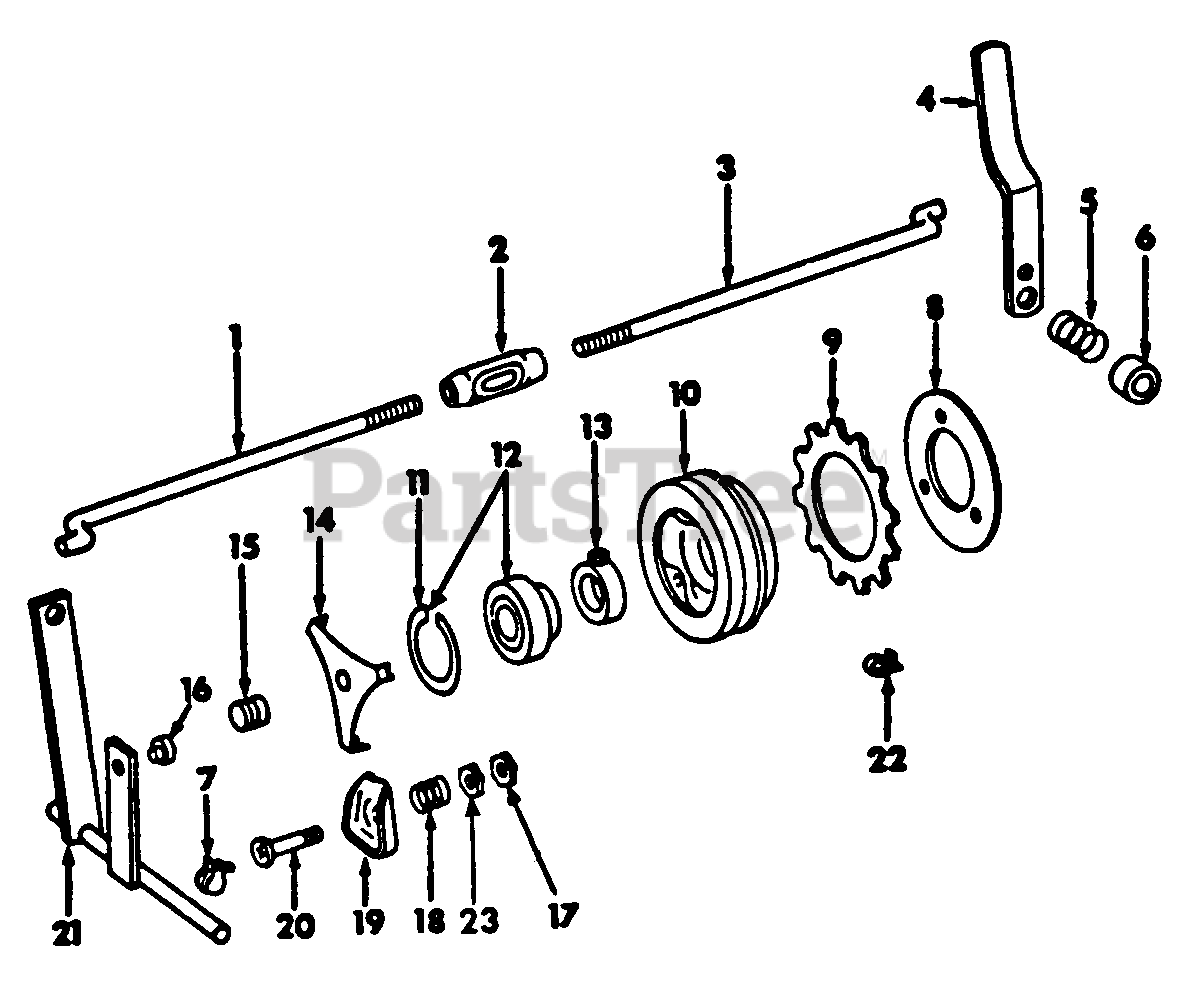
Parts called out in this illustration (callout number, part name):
1	Rod, Clutch
2	Turnbuckle, Rod
3	Rod, Rear Clutch
4	Lever Assy, Handle
5	Spring, 15 Ga Compression
6	Spacer, Spring
7	Clamp, Locating
8	Plate, Pressure
10	Pulley, Mower Actuating
11	Ring, Bearing Snap
12	Bearing w/Snap Ring, Ball
13	Collar w/Set Screw & Lock Nut, Brg
15	Button, Thrust
16	Button, Wear
17	Nut, 1/4-28 Hex Jam
18	Spring, Compression
19	Lever, Throw-Out
20	Screw, Special Machine
21	Shaft w/Button 478 483 R1, Clutch
22	Spring, Friction Disc
23	Nut, 1/4-28 Hex
